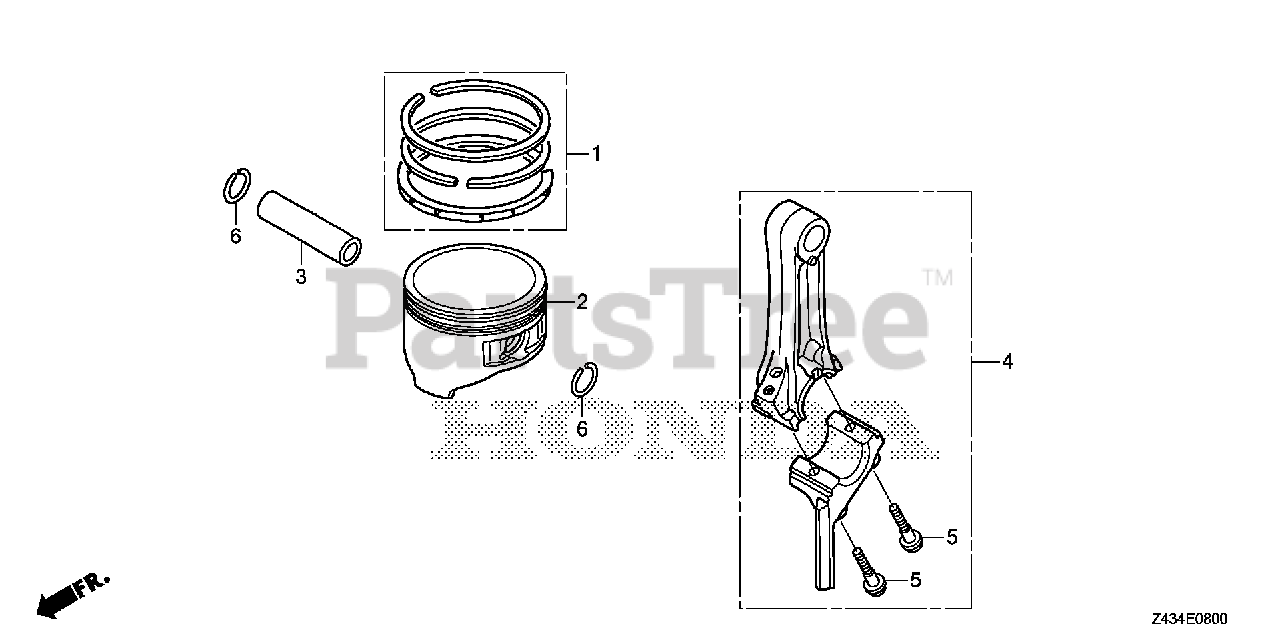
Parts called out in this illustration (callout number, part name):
1	RING SET, PISTON (STD) (TEIKOKU)
2	PISTON
3	PIN, PISTON
4	ROD ASSY., CONNECTING
5	BOLT, CONNECTING ROD
6	CLIP, PISTON PIN (13MM)
